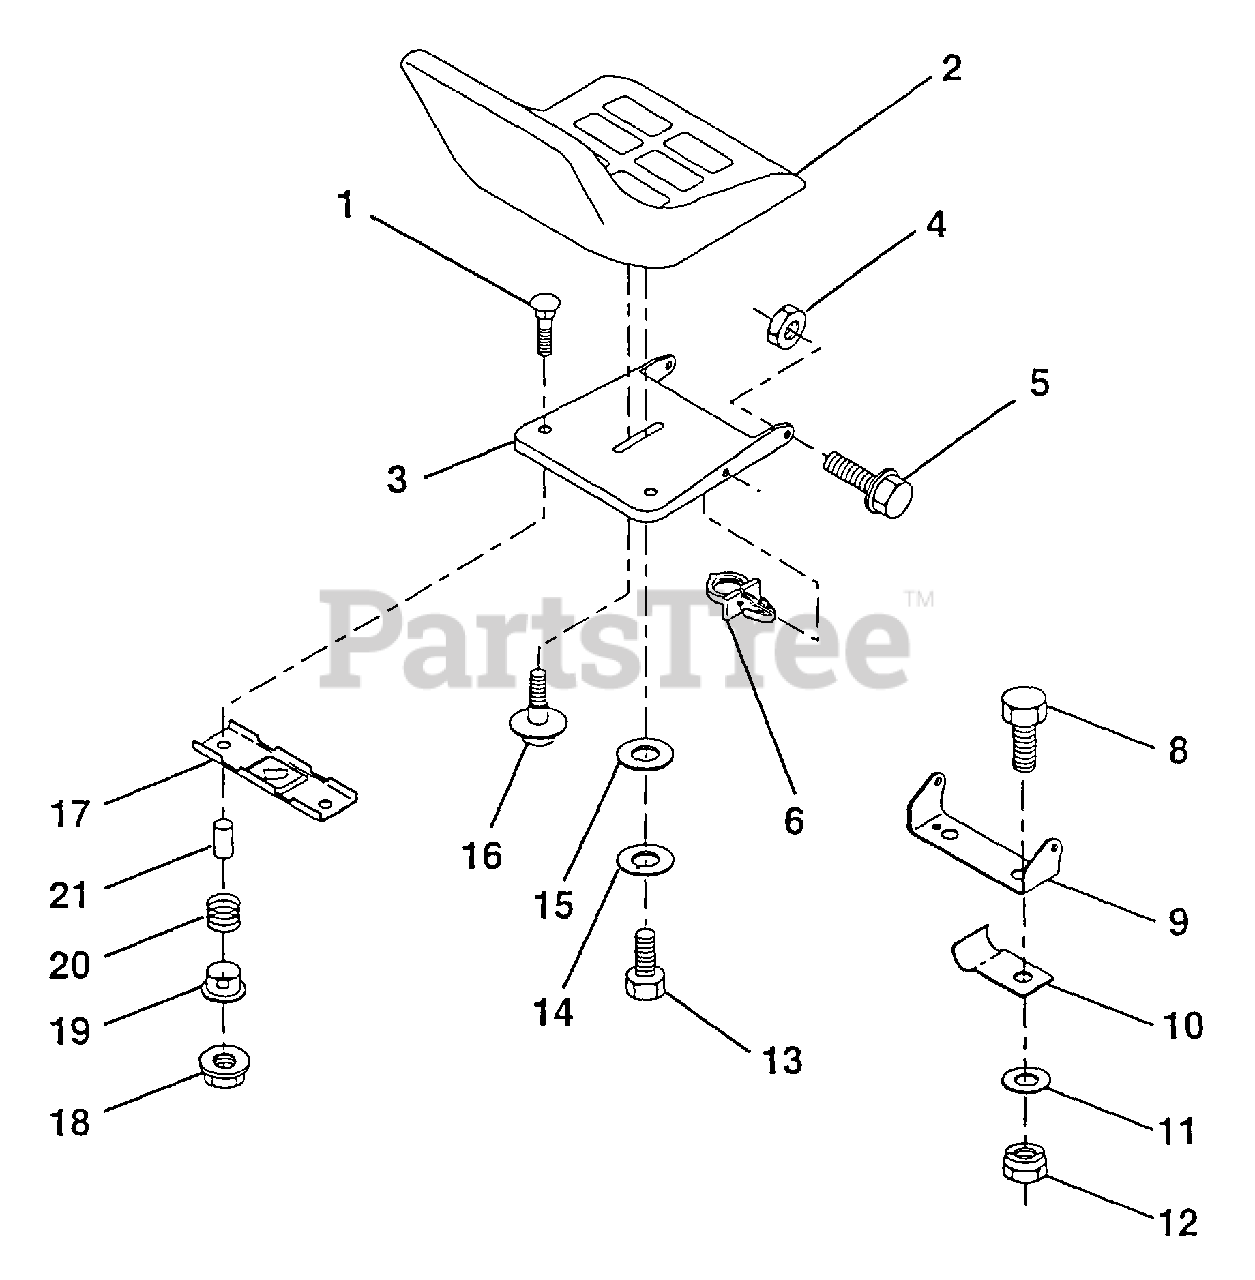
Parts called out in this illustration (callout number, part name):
1	Bolt, Carriage 1/4-20 x 1-3/8 (AYP part number)
2	Seat (AYP part number)
3	Pan, Seat (AYP part number)
4	Locknut, Hex w/Ins 5/16-18
5	Bolt, Shoulder 5/16-18 UNC (AYP part number)
6	Clip, Push-In Hinged
8	Bolt, Fin Hex 3/8-16 UNC x 1
9	Bracket, Pivot Seat
10	Clip, Insulated
11	Washer 12/32 x 2 x 10 Ga.
12	Nut, Lock Hex w/Wsh 3/8-16
13	Bolt Hex 1/2-13 x 7/8 (AYP part number)
14	Washer Lock Hvy. Hlicl Spring 1/2
15	Washer, 17/32 x 1-3/16 x 12 Ga.
16	Bolt, Shoulder
17	Bracket, Switch, Mounting
18	Nut, Hex Large Flange Lock (AYP part number)
19	Bushing, Snap
20	Spring, Compression
21	Spacer, Split 28 Id. x .88 Lg.
